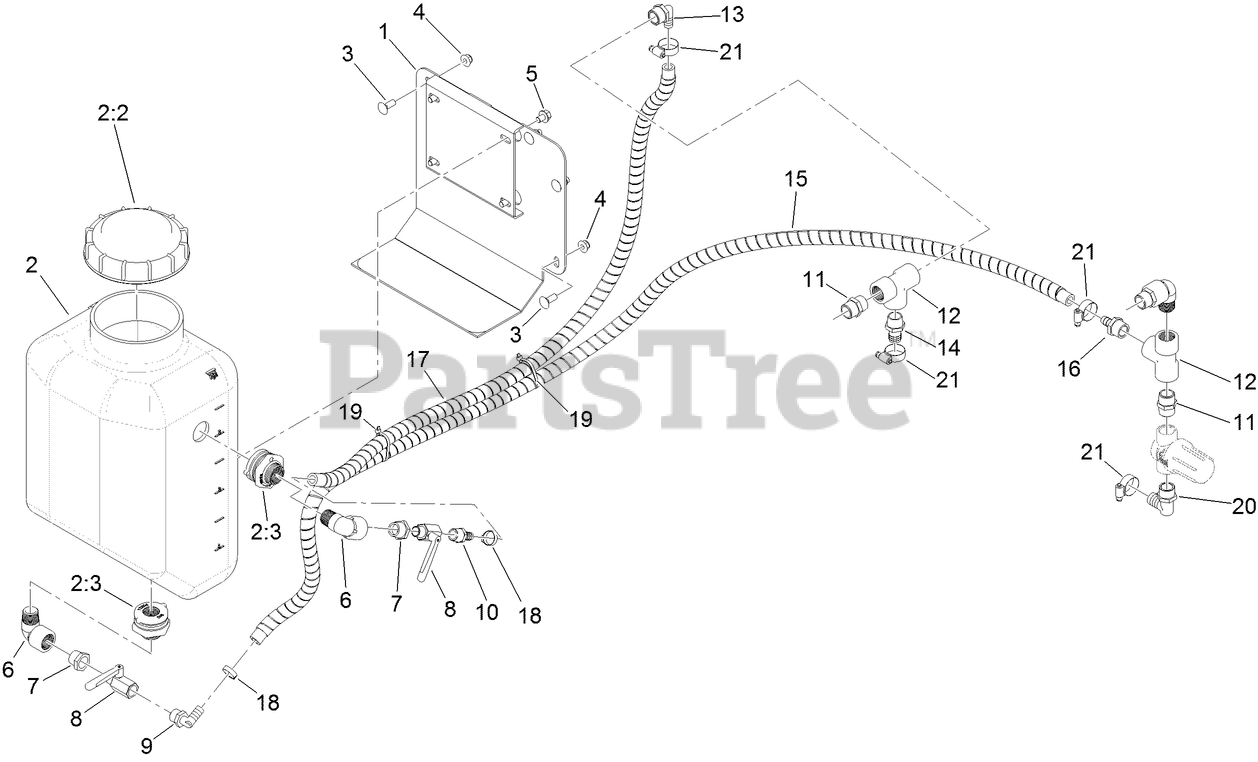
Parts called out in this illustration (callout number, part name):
1	MOUNT-AUX/ISO, 7GAL LT
2	ASM-TANK, AUX/ISO, 7GAL LT
2:2	CAP-TANK, SPRAY
2:3	FITTING-BULKHEAD
3	SCREW-CARR
4	NUT-HEX FLANGE
5	SCREW-HHF
6	ELBOW-90 DEG
7	REDUCER-BUSHING, PLASTIC
8	VALVE-CHROME, 1/2
9	FITTING-ELBOW, HOSEBARB
10	FITTING-HOSEBARB
11	FITTING-NIPPLE
12	FITTING-TEE
13	FITTING-ELBOW, 90
14	HOSEBARB
15	HOSE-SPRAY, WRAPPED
16	FITTING-STRAIGHT
17	HOSE-SPRAY, WRAPPED
18	CLAMP-OETIKER, 167
19	TIE-CABLE
20	FITTING-ELBOW, 90
21	CLAMP-HOSE
